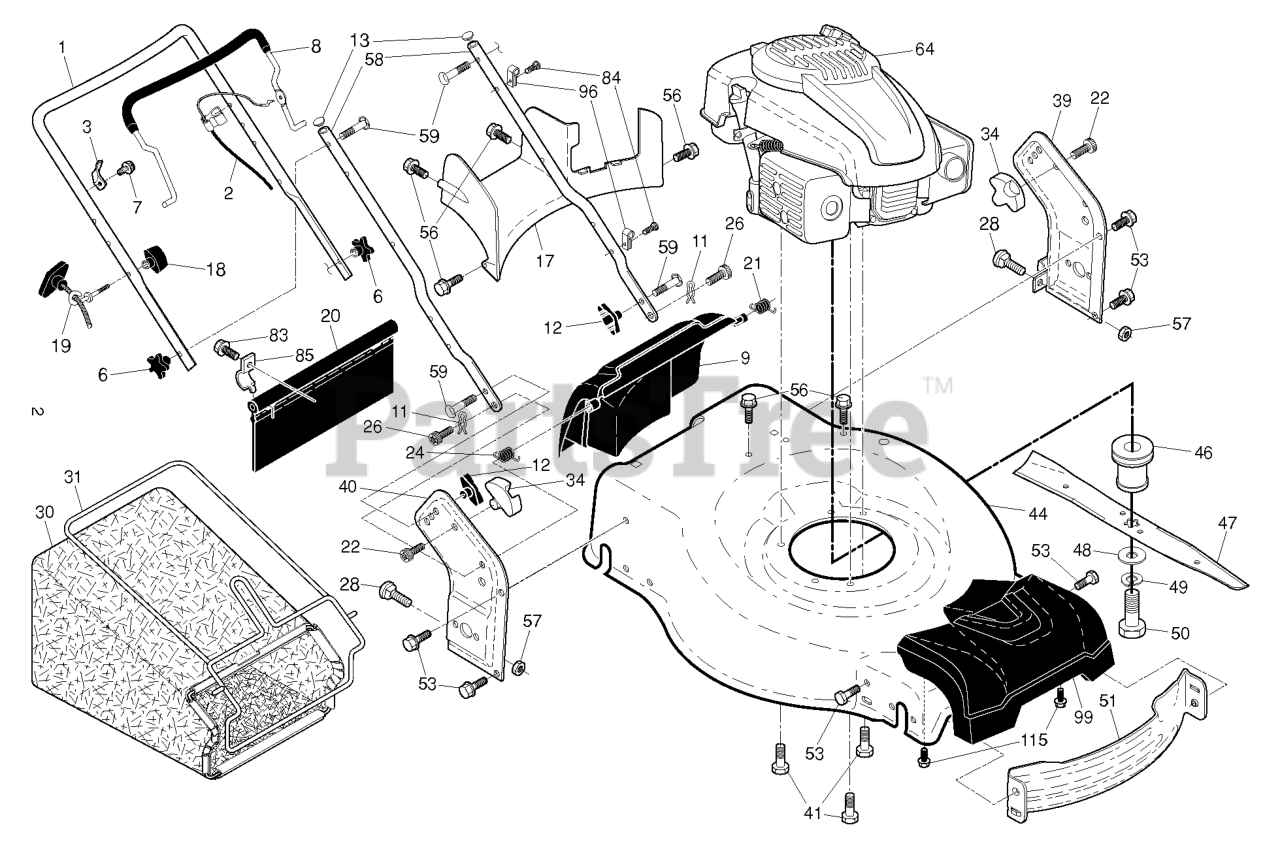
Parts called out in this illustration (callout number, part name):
1	HANDLE.UP.DST.SS/VS.FG/RGD.CRE
2	RP.CABLE.MZR.RGD.PLUS.STRT
3	BRACKET.UPSTOP.RT
6	KNOB.HANDLE.PLASTIC.STAR.BLACK
8	RP BAIL.OVER.MOLD.STRAIGHT.ORG
9	DOOR.REAR.ASM.22+GEN.FG/RG.498
11	COTTER.HAIRPIN.DOOR/HANDLE.PIV
12	KNOB, DEFLECTOR
13	PLUG.PLASTIC.7/8".14-20.GAUGE
17	BAFFLE.REAR.22+RGD.AWD.PLASTIC
18	T-KNOB.NEW ROPE GUIDE
19	GUIDE.ROPE.BLK.ZINC.CHROM
20	SKIRT.REAR.22PLUS.RGD.LW(2 2MC
21	SPRING.LH.BLACK
22	SCREW.PAN.HEAD.#10
24	SPRING.RH.GRAY
26	SCREW,DOOR/HANDLE.PIVOT
28	BOLT
30	GBAG.AWD.HUSQ.A361029EM.GRY/SL
31	RB FRAME.GBAG.22PLUS
34	BRACKET.GRASSBAG.ATTACHING.BLK
39	BRACKET.ASM.HANDLE.LT.22+.GREY
40	BRACKET.ASM.HANDLE.RT.22+.GREY
41	BOLT 3/8-16X1-1/8
44	HOUSING.22+AWD.RR.HD.WO.668TRI
46	ADAPTER.BLADE.25MM.3MPH
47	BLADE.22PLUS
48	WASHER,HARDEN
49	LOCKWASHER
50	SCREW, HEX HD 3/8-24 X 1-3/8
51	BAFFLE.FRONT.22.PLUS
53	BOLT.5/16HEX.WHS.HD
56	SCREW.HX.13X.750
57	NUT.FLANGE.5/16
58	HANDLE.LOWER.22+BT.2PC.GRY
59	BOLT, HANDLE 5/16-18X1.75
83	TAPPING SCREW
84	FASTENER.PUSH.O.250X0.783
85	BRACKET.SKIRT.22+.BZP
96	CLIP.CABLE.BLK
99	COVER.ASSEMBLY.FRONT.22+AWD
115	SCREW.SHOULDER.5/16X1.375
